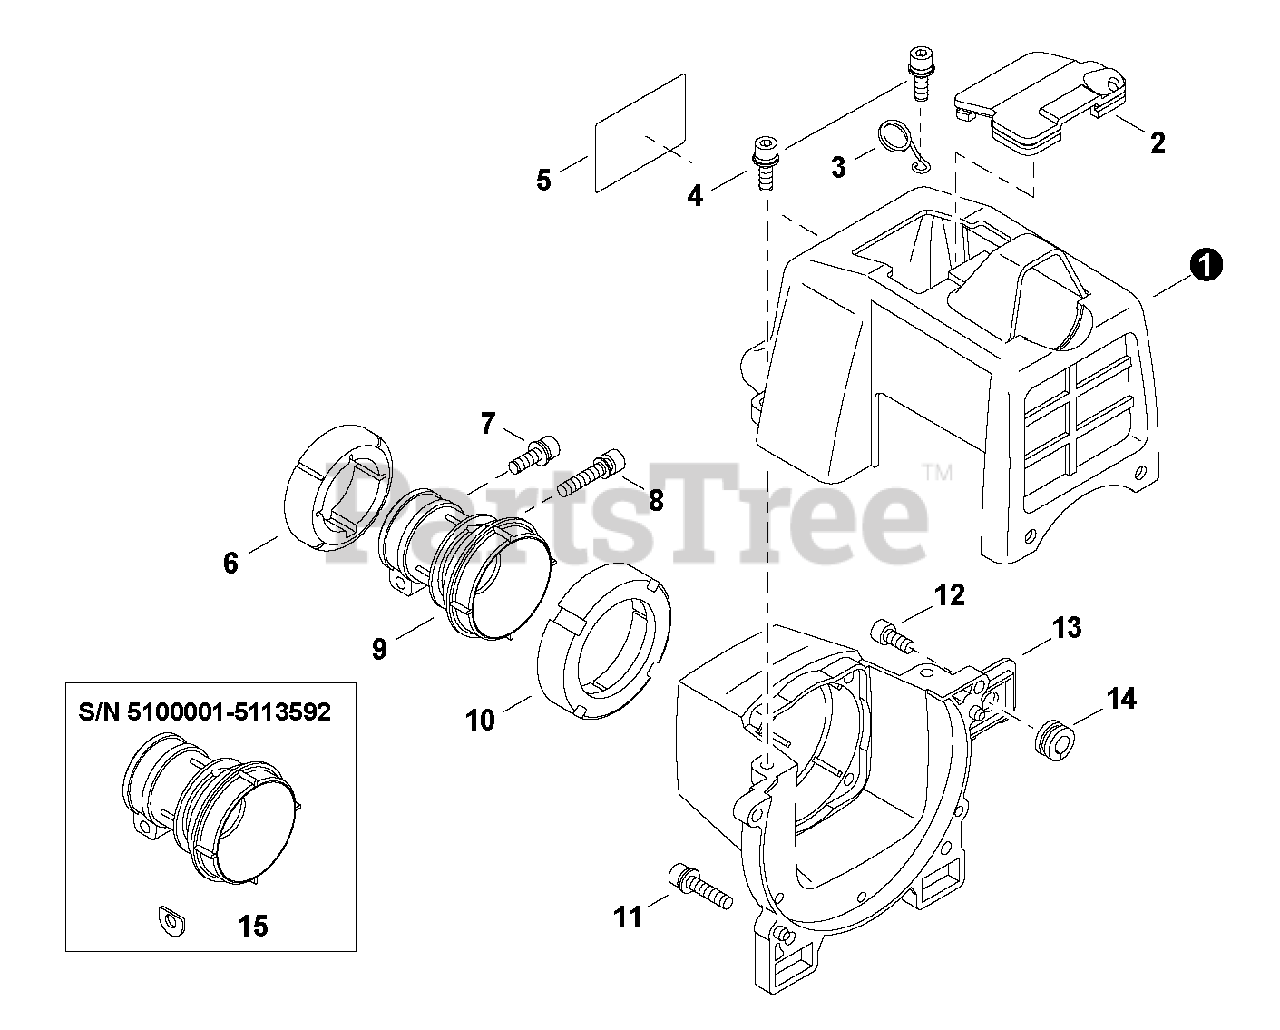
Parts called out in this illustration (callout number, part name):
1	COVER, ENGINE
2	CAP, DUST
3	HOLDER, THROTTLE CABLE
4	BOLT M5×16
5	LABEL, MODEL
6	HOLDER, FRONT CUSHION
7	BOLT M5×16
8	BOLT M6×28
9	CUSHION
10	HOLDER, REAR CUSHION
11	BOLT M5×30
12	BOLT M5×18
13	COVER, FAN
14	GROMMET
